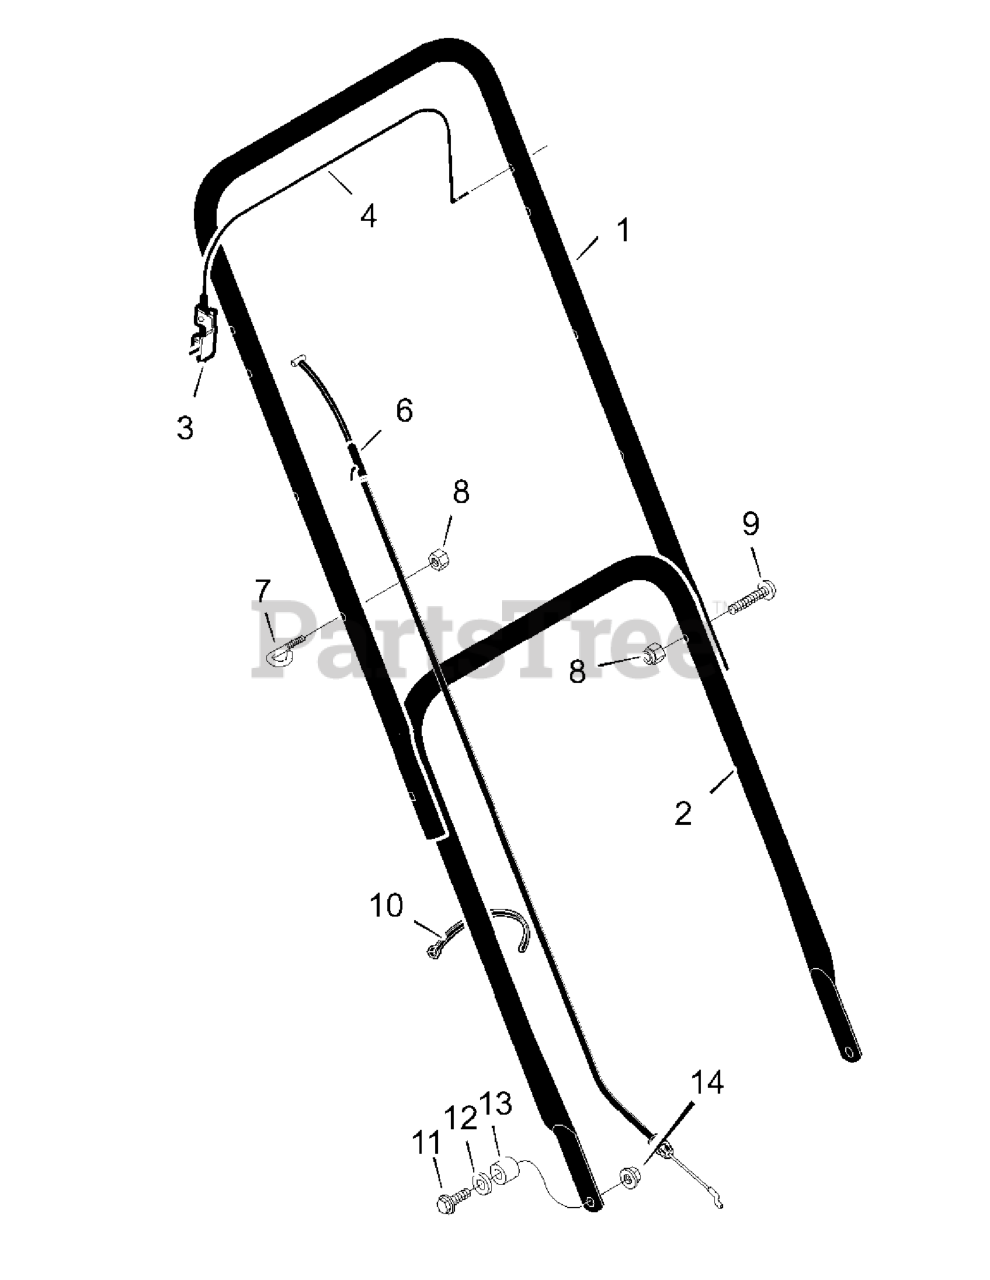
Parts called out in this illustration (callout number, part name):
1	Handle, Upper (Black)
2	Handle, Lower (Black)
3	Bracket, Stop Lever
4	Lever, Stop
6	Engine Stop Cable
7	GUIDE, ROPE
8	Locknut
10	Fastener, Cable
11	Bolt
14	Nut
